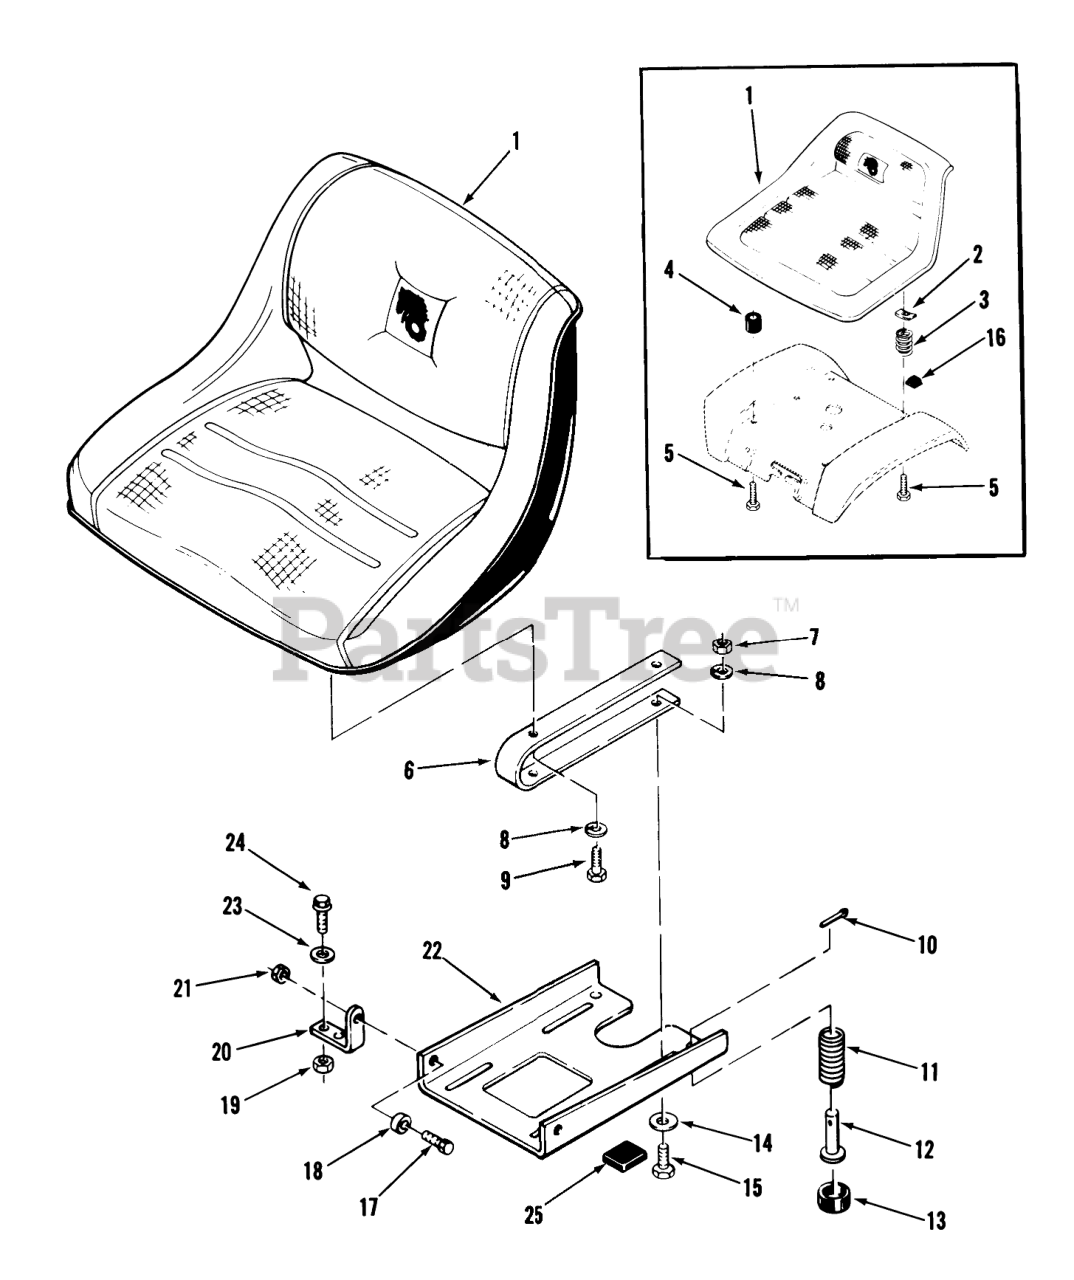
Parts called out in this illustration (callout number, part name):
1	Seat
2	NUT-PUSH
3	SPRING
4	GROMMET-RUBBER
5	SPECIAL BOLT
5	HHCS
6	Spring
7	Nut
8	Lockwasher
9	HHCS
10	Cotter Pin
11	SPRING
14	WASHER 5/16 SAE
15	Bolt
16	BUMPER
17	HHCS
18	BUSHING
19	Nut
20	BRACKET-PIVOT
21	Nut
22	Pivot Plate
23	WASHER 5/16 SAE
24	Bolt
25	WASHER
